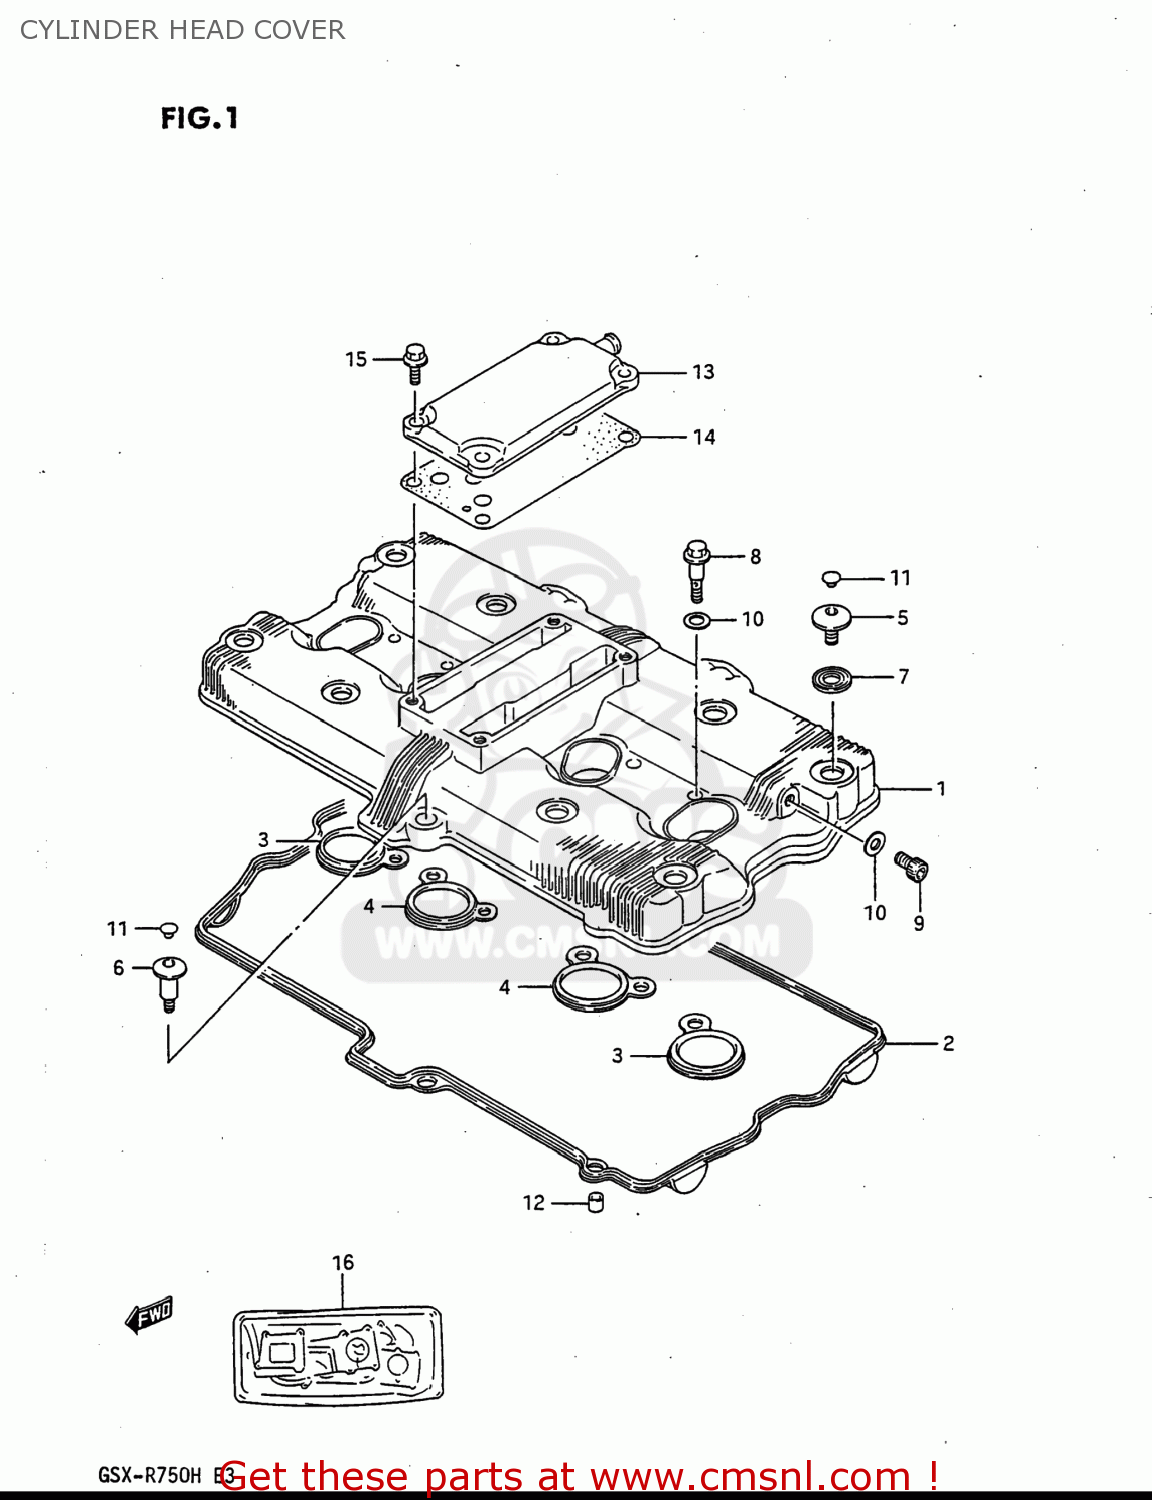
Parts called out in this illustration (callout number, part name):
1	COVER,CYLINDER HEAD
2	GASKET,CYLINDER HEAD COVER (NAS)
3	GASKET (NAS)
4	GASKET,HEAD COVER NO.3 (NAS)
5	BOLT(7X17.5)
6	BOLT(7X31)
7	WASHER
8	BOLT,UNION 8X35
9	PLUG, HEAD COVER
10	GASKET 8.2X14X1 (NAS)
11	CAP(OD:10)
12	PIN
13	COVER,BREATHER
14	GASKET (NAS)
15	BOLT
16	GASKET SET
